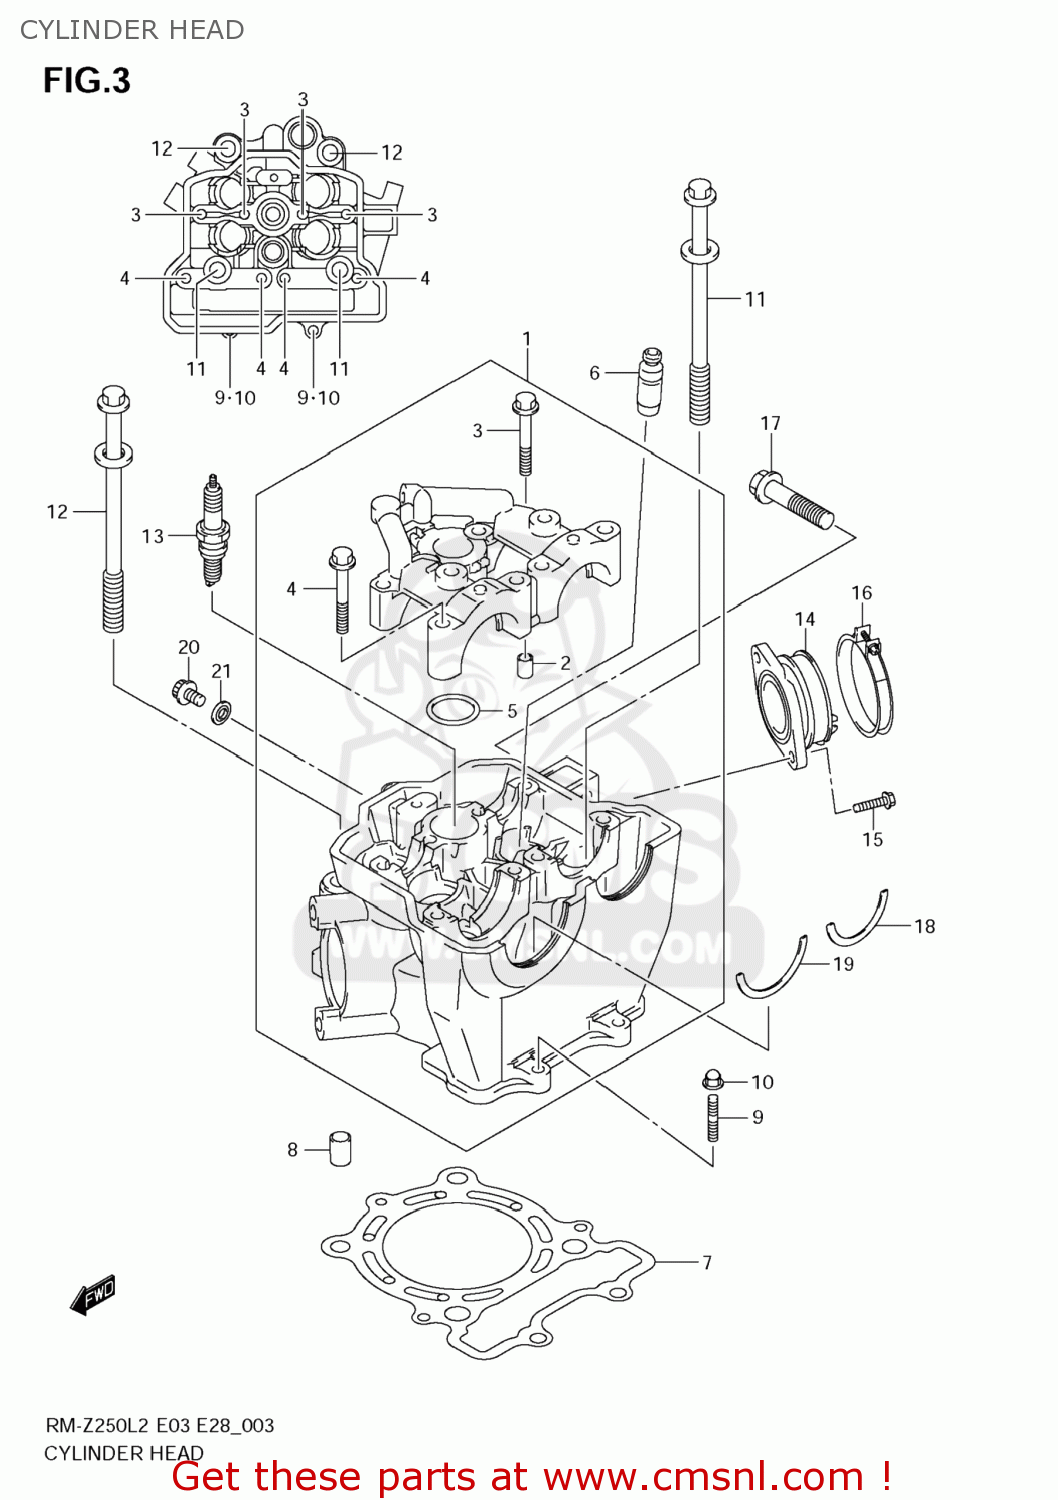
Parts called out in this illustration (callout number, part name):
1	HEAD ASSY,CYLINDER
2	PIN(6.2X8X11)
3	BOLT(6X40)
4	BOLT(6X45)
5	O RING(D:2.4,ID:25.7)
6	GUIDE,VALVE(OS:0.3)
7	GASKET,CYLINDER HEAD (NAS)
8	PIN
9	BOLT,STUD
10	NUT
11	BOLT,CYLINDER HEAD
12	BOLT,CYLINDER HEAD
13	PLUG,SPARK(CR8EIA-10)
14	PIPE ASSY,INTAKE
15	BOLT
16	CLAMP,INTAKE PIPE
17	BOLT(10X50)
18	C RING,CAMSHAFT
19	C RING,CAMSHAFT
20	BOLT
21	GASKET(5.8X13X1.2) (NAS)
